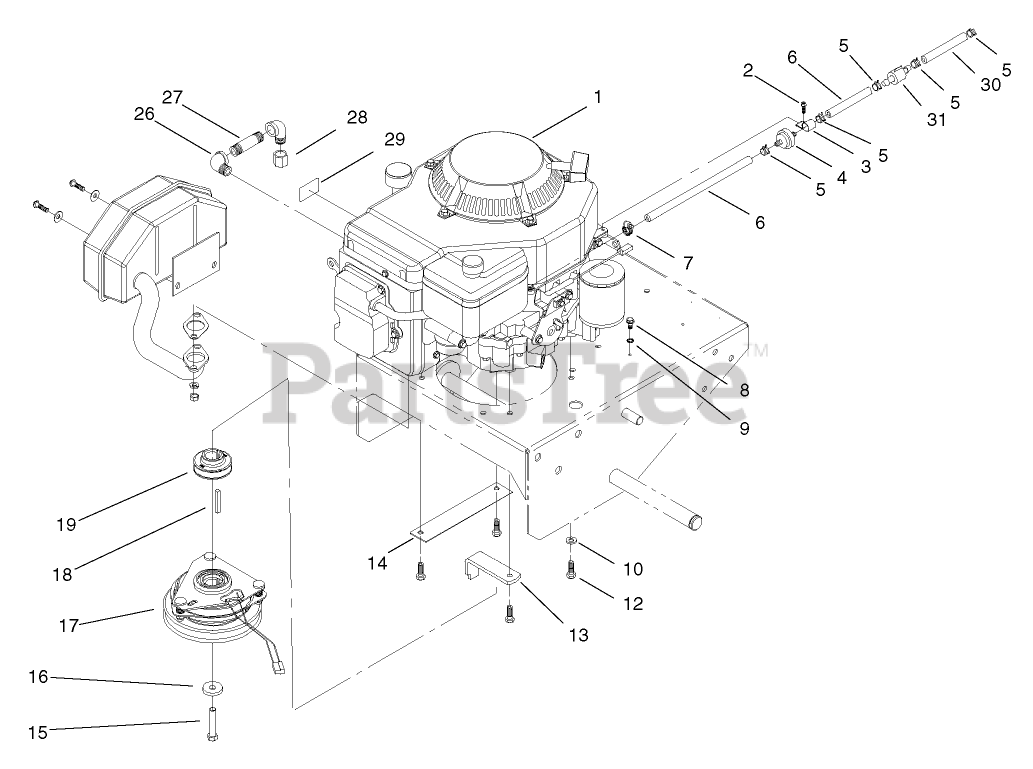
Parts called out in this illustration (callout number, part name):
2	SCREW-SHWH
3	CLAMP-CABLE
4	FILTER-FUEL
5	CLAMP-HOSE
6	HOSE-FUEL
7	CLAMP-WORM
8	SCREW
9	WASHER-LOCK/EXT
10	WASHER-PLAIN
12	SCREW-HH
13	RETAINER-CLUTCH
14	GUARD-PULLEY
15	SCREW-HH
16	WASHER
17	CLUTCH/BRAKE
18	KEY-SQUARE
19	PULLEY-DRIVE
26	ELBOW-STREET, 90 DEG
27	NIPPLE-PIPE
28	CAP-PIPE
29	DECAL-SURFACE, HOT
30	HOSE-FUEL
31	VALVE-FUEL
